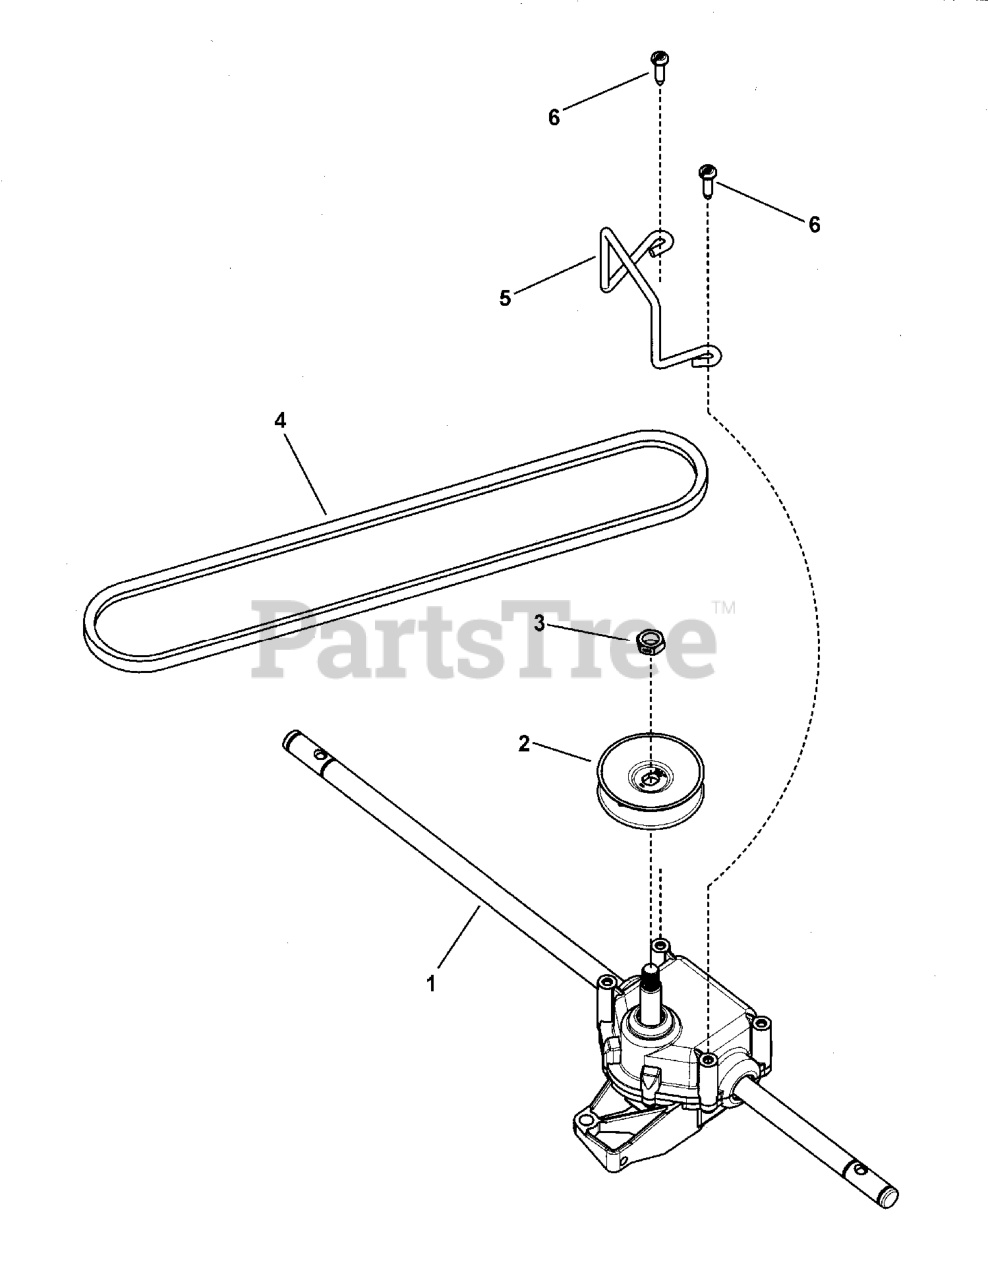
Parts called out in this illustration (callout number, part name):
1	TRANSMISSION, VS, RWD
2	PULLEY, TRANS VAR SPD LC WBM
3	NUT, 3/8-16 Hex Center Lock, YZ
4	BELT, 3L, TRACTION DRIVE, 22" WBM, RWD
5	BELT GUIDE, TRANSMISSION
6	SCREW, PHST, #10-16 X 3/4, COMBO
